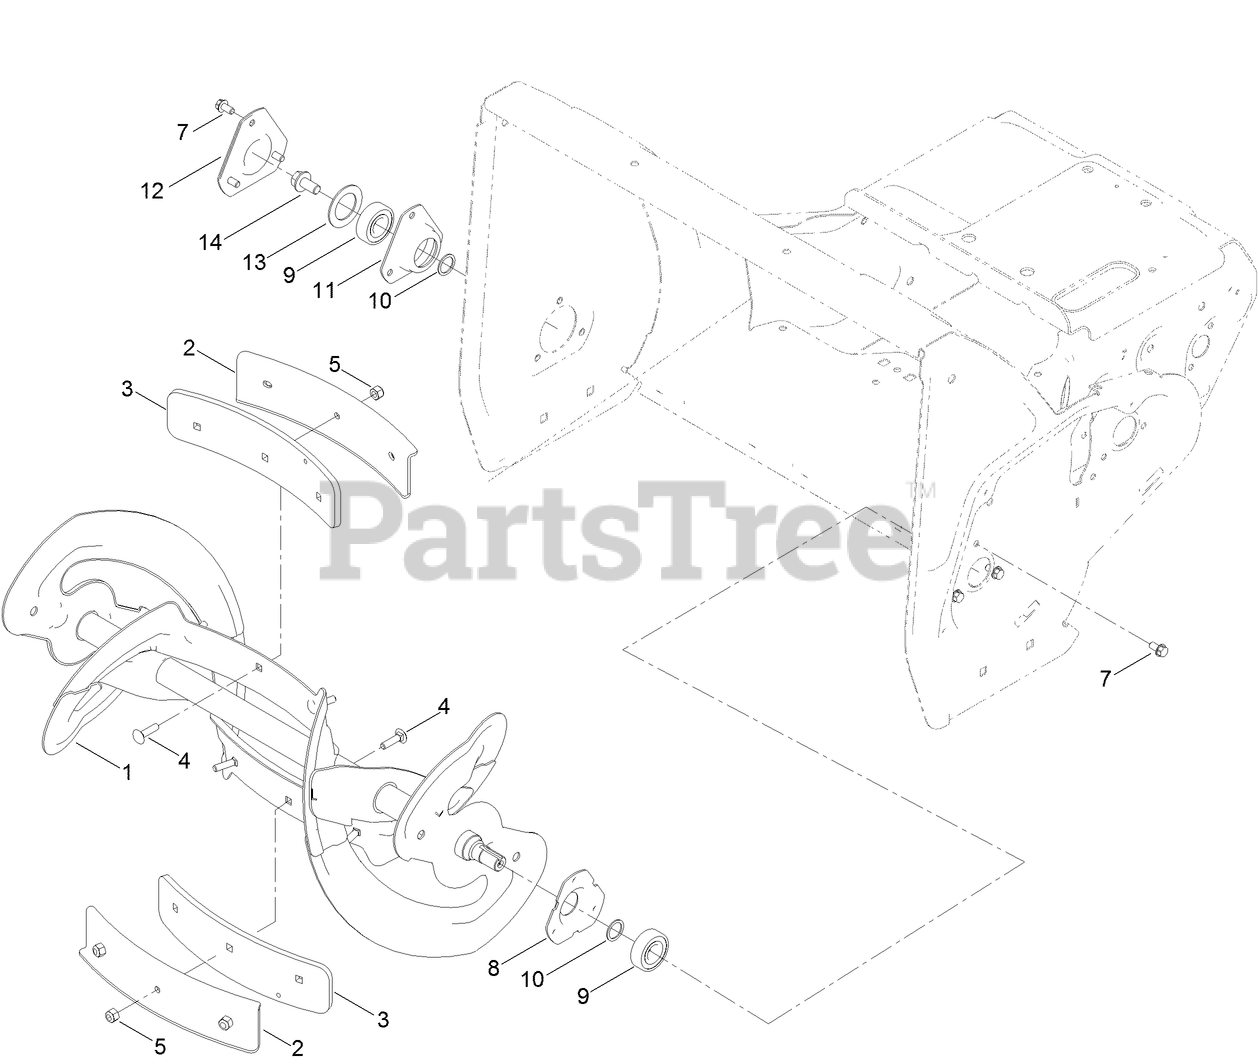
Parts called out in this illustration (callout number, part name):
1	ROTOR ASM
2	SUPPORT-CENTER, ROTOR
3	PADDLE-CENTER
4	SCREW-CARR
5	NUT-LOCK, NI
7	SCREW-HWH
8	FLANGE-BEARING
9	BEARING-BALL
10	WASHER-THRUST
11	FLANGE-BEARING
12	CAP-BEARING
13	WASHER-RUBBER
14	SCREW-HWH
